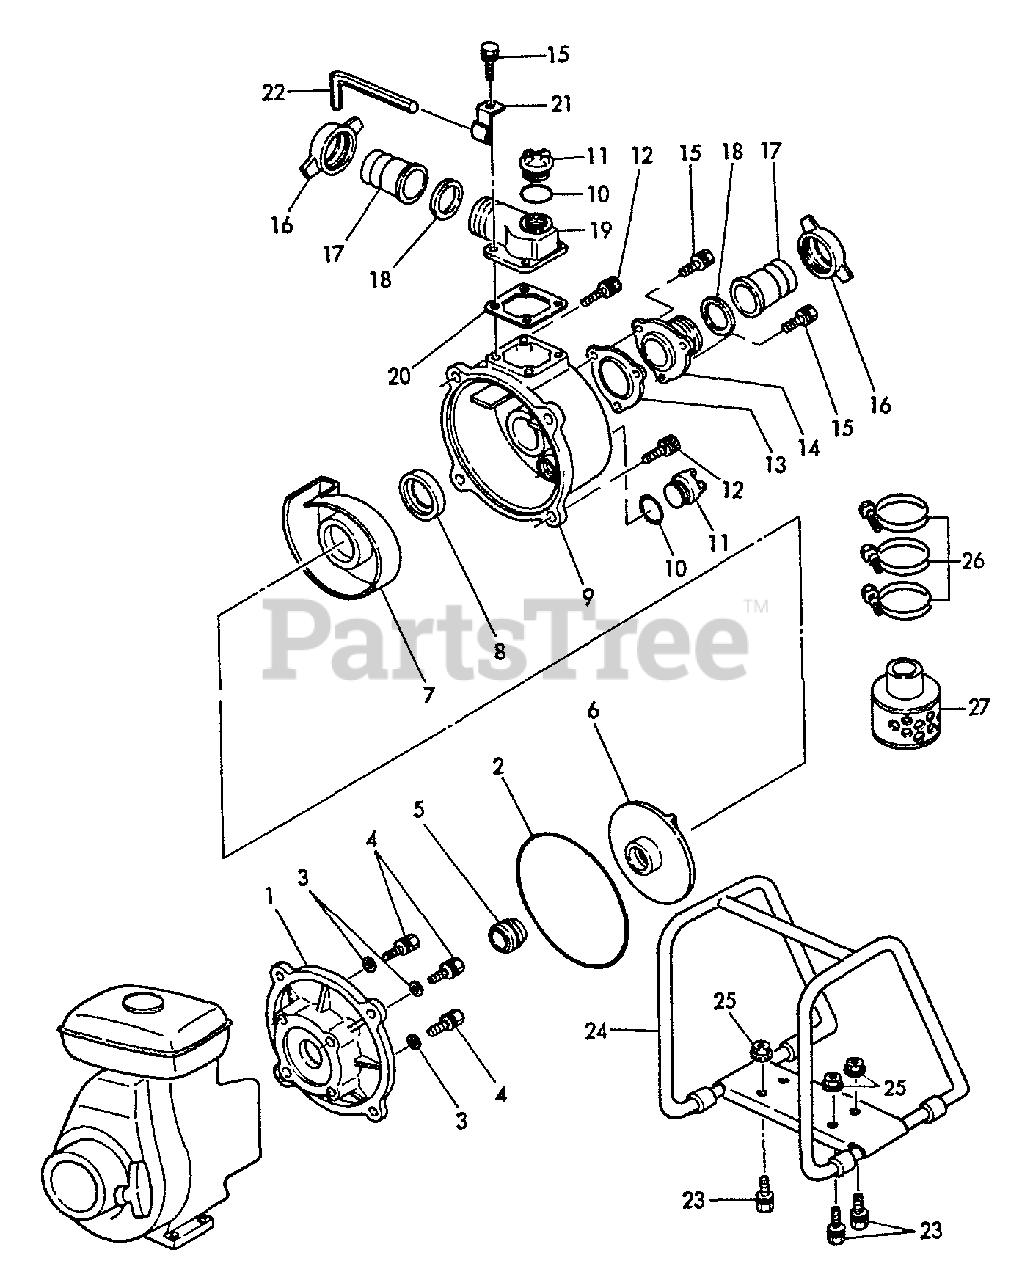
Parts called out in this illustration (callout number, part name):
1	COVER, CASING
3	GASKET
4	BOLT - 8×48
5	SEAL, MECHANICAL
6	IMPELLER
7	CASING, INNER
8	GASKET
9	CASING
12	BOLT
13	VALVE, CHECK
14	CASE (NPT), VALVE
15	BOLT - 8×25
16	JOINT (AL-NPT), HOSE
18	GASKET
19	BEND (NPT), DELIVERY
20	GASKET
21	HOOK
22	WRENCH, SOCKET
23	BOLT
24	FRAME
25	NUT - FLANGE
26	BAND, HOSE
27	STRAINER, DEBRIS
